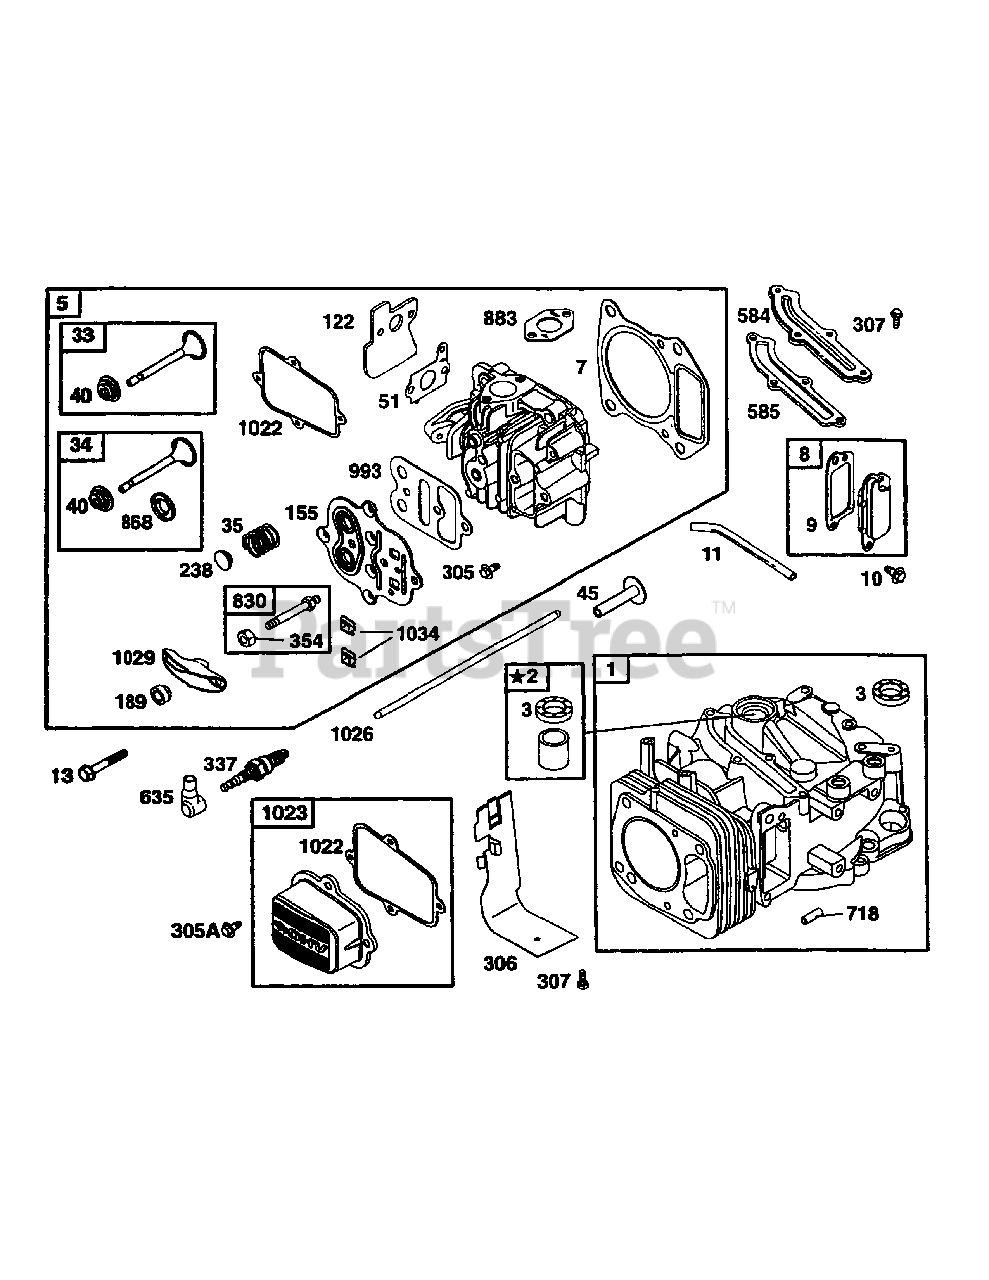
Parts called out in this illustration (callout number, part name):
1	Cylinder Assembly
2	Bushing
3	Seal-Oil
5	Cylinder Head
7	Cylinder Head Gasket
8	Breather Assembly
9	Breather Gasket
10	Screw-Hex
11	Breather Tube
13	Screw-Hex
33	Exhaust Valve
34	Intake Valve
35	Valve Spring
40	Valve Retainer
45	Valve Tappet
51	Intake Gasket
122	Carburetor Spacer
155	Cylinder Head Plate
189	Rocker Arm Ball
238	Valve Cap
305	Screw-Hex
305A	Screw-Hex
306	Cylinder Shield
307	Screw-Hex
337	Spark Plug
354	Lock Nut
584	Breather Passage Cover
585	Breather Passage Gasket
635	Spark Plug Boot
718	Locating Pin
830	Rocker Arm Stud
868	Valve Seal
883	Exhaust Gasket
993	Plate Gasket
1022	Rocker Cover Gasket
1023	Rocker Cover
1026	Push Rod
1029	Rocker Arm
1034	Push Rod Guide
